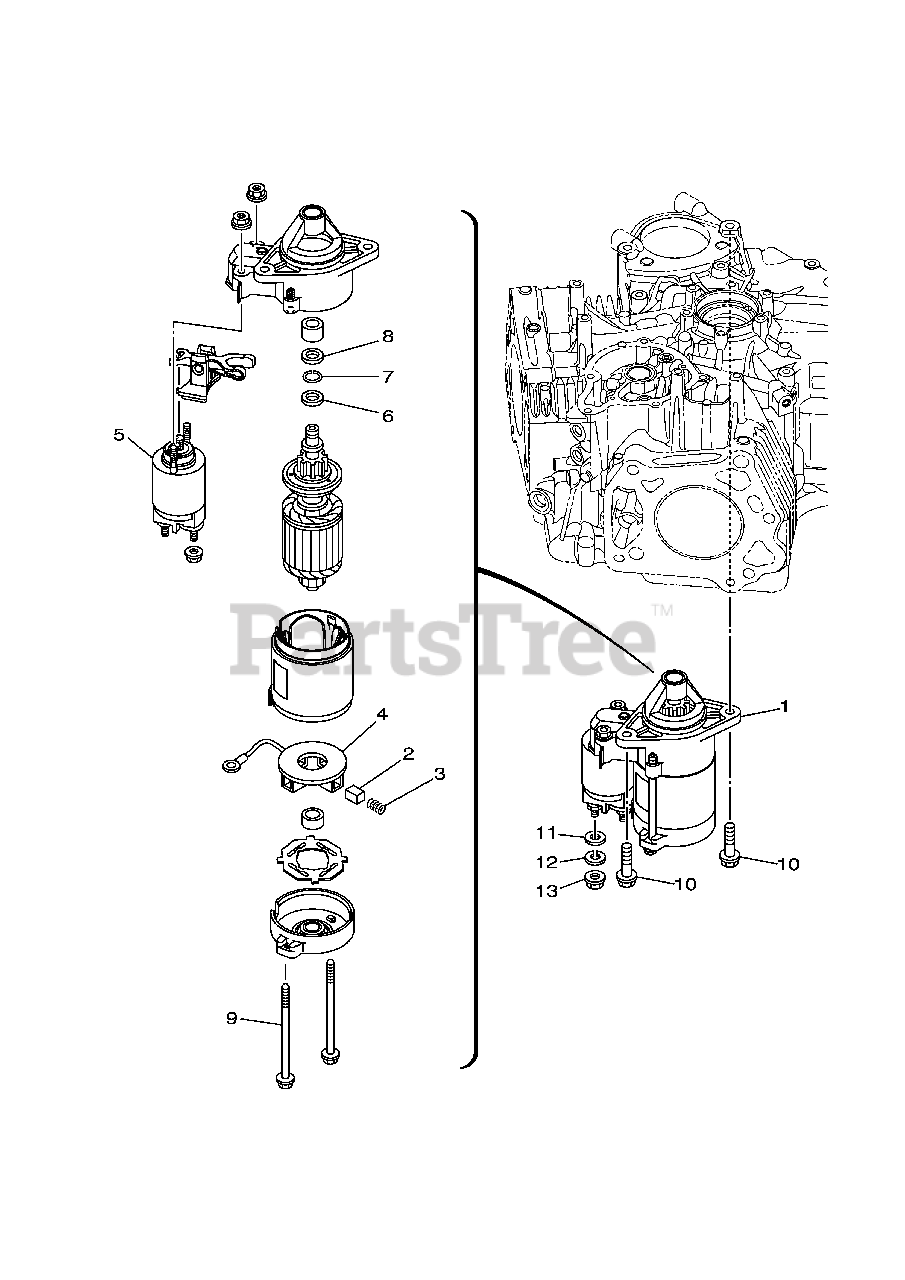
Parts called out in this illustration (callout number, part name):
1	STARTING MOTOR ASSY
3	SPRING, BRUSH
4	BRUSH HOLDER ASSY
5	STARTING SWITCH ASSY
6	RING, STOP
10	BOLT, FLANGE
11	WASHER, PLATE
12	WASHER, SPRING
13	NUT, HEXAGON
